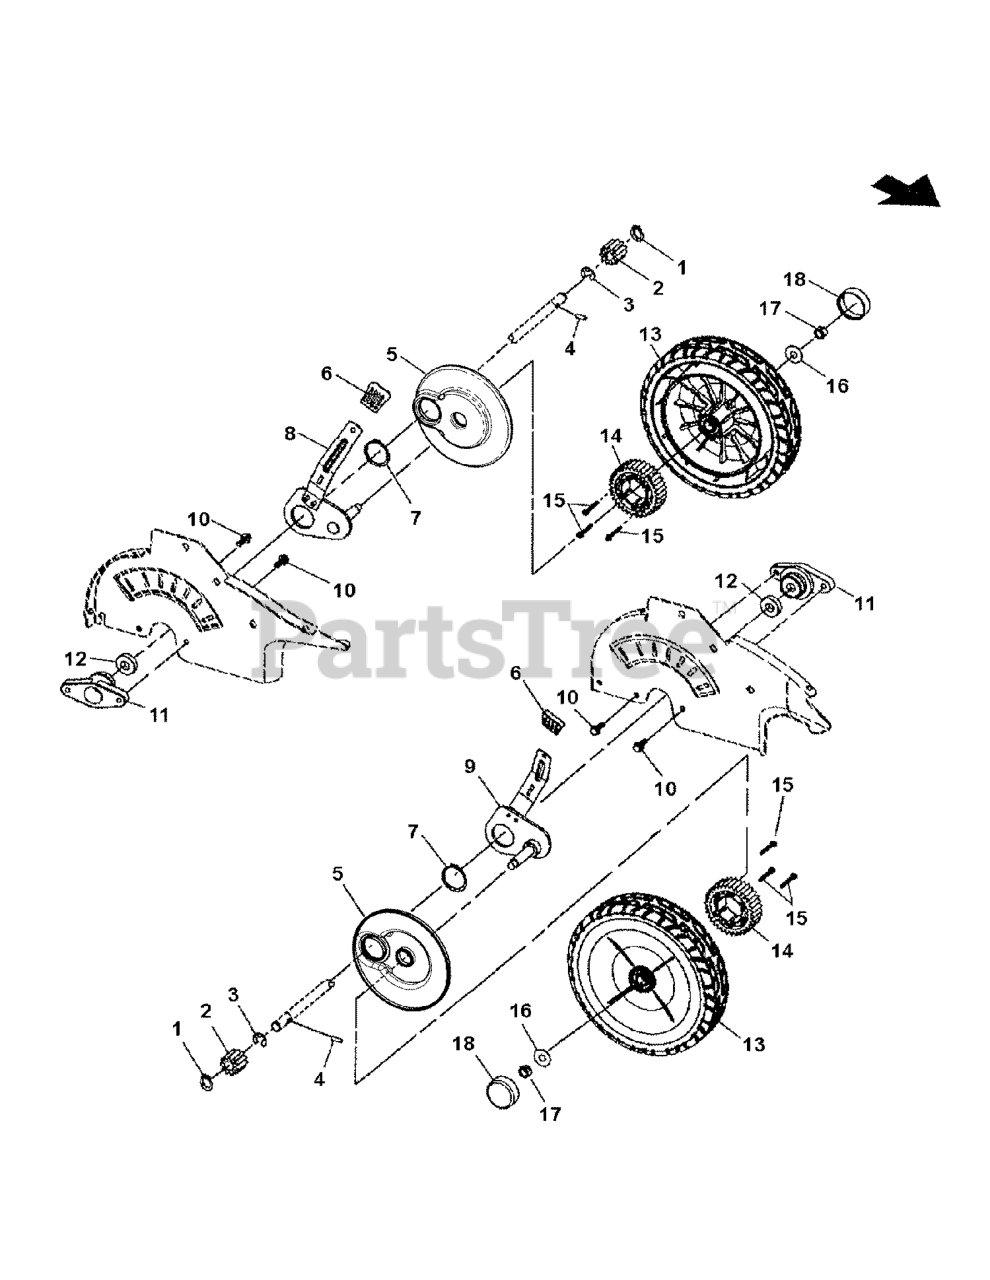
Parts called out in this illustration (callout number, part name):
1	RETAINING RING
2	GEAR, PINION
3	RETAINING RING
4	PIN, AXLE
5	SHIELD, DUST, 21" WBM, RD
6	GRIP, HT LATCH
7	SNAP RING, 1-3/8
8	ASSY, AXLE ARM, LEFT REAR
9	ASSY, AXLE ARM, RIGHT REAR
10	HFLB, 1/4-20X3/4
11	HOUSING, AXLE BEARING
12	BEARING, BALL, AXLE
13	ASSY, WHEEL, W/BEARING 9" ST TRD
14	GEAR, EXTERNAL WHEEL
15	HWST, #8 X 1-1/4, HI-LO
16	WASHER, FLAT, 1" OD X .387 ID
17	HCLN, 3/8-16 YZ
18	HUBCAP, ROUND, JD YELLOW
